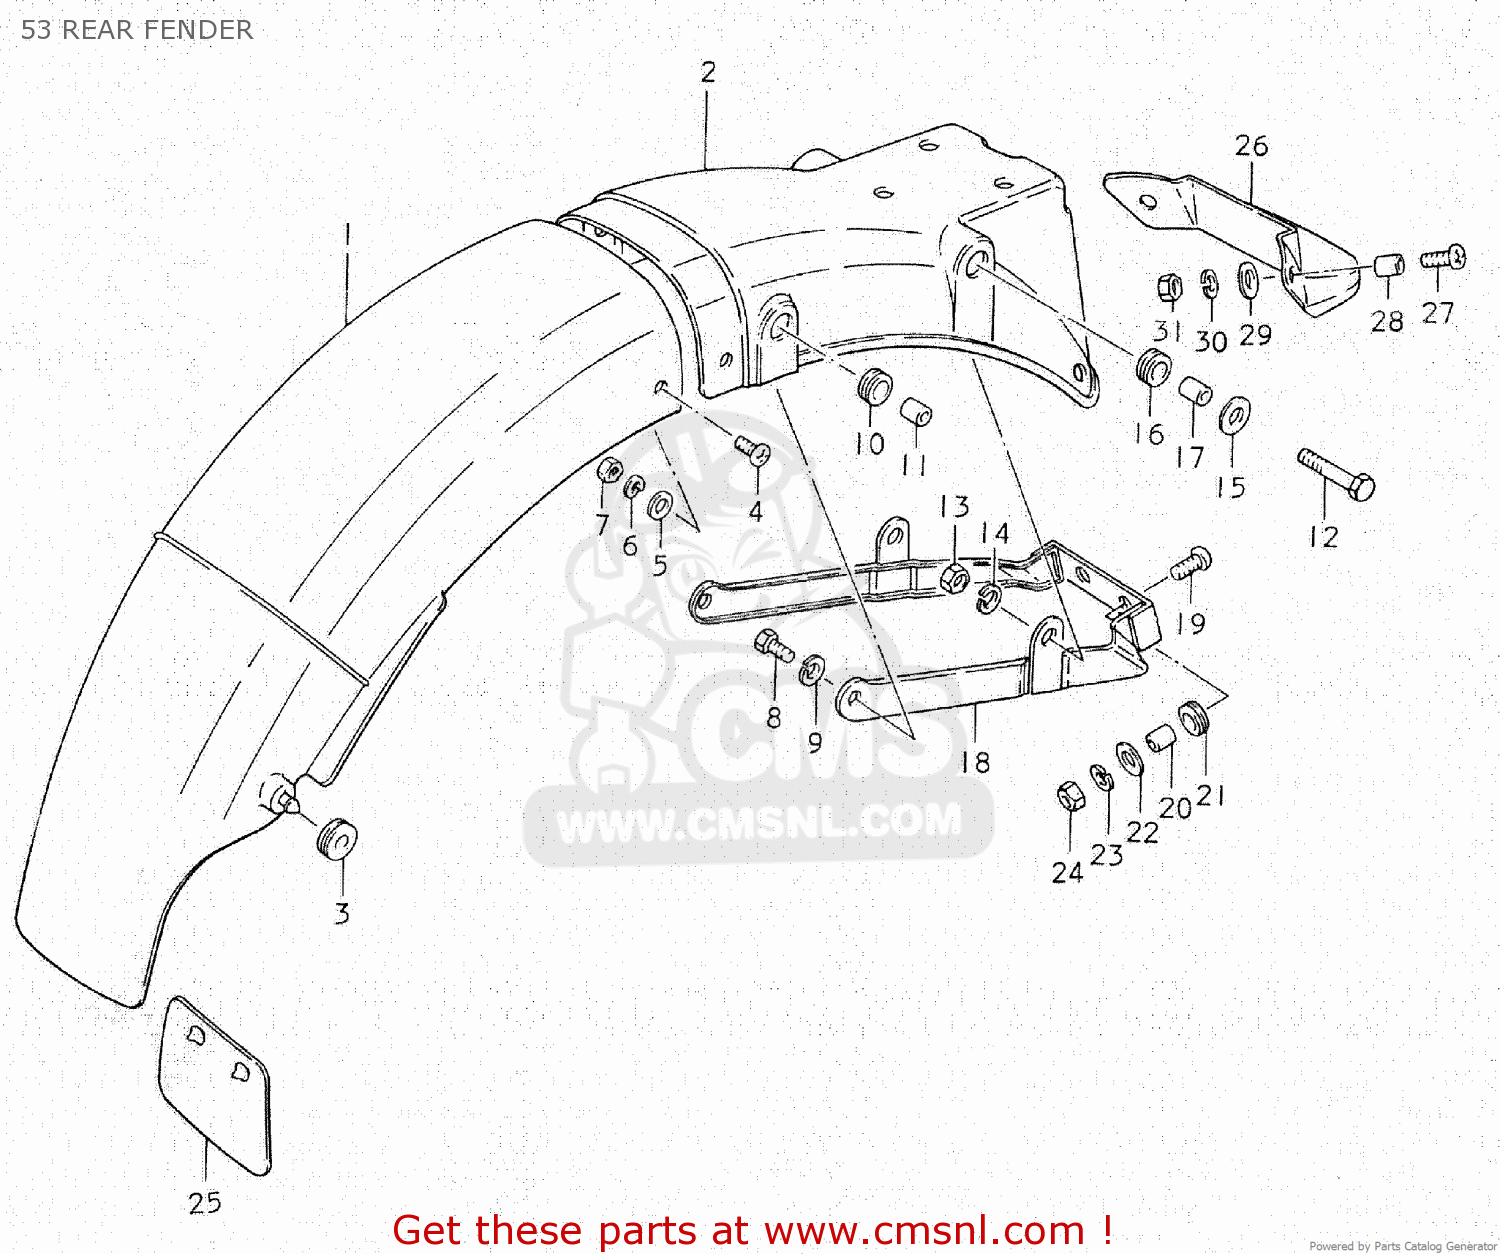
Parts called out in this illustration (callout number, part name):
1	FENDER,REAR
2	BODY,REAR FENDER,REAR
3	CUSHION
4	SCREW
5	WASHER (5.5X16X1.2)
6	LOCK WASHER
7	NUT
8	BOLT
9	LOCK WASHER
10	CUSHION
11	SPACER(6.1X9X7.5)
12	BOLT
13	NUT
14	LOCK WASHER
15	WASHER(8.5X26X1.2)
16	CUSHION
17	SPACER (8.2X12X7.5)
18	REINFORCEMENT,REAR FENDER
19	SCREW
20	SPACER (6.1X9X9)
21	CUSHION
22	WASHER(6,5X22X1.6)
23	LOCK WASHER
24	NUT
25	GUIDE,RR FENDER MUD
26	EXTENSION,REAR FENDER
27	SCREW (6X15)
28	SPACER(6.2X8.3X5.7)
29	WASHER(6.5X18X1)
30	LOCK WASHER
31	NUT
